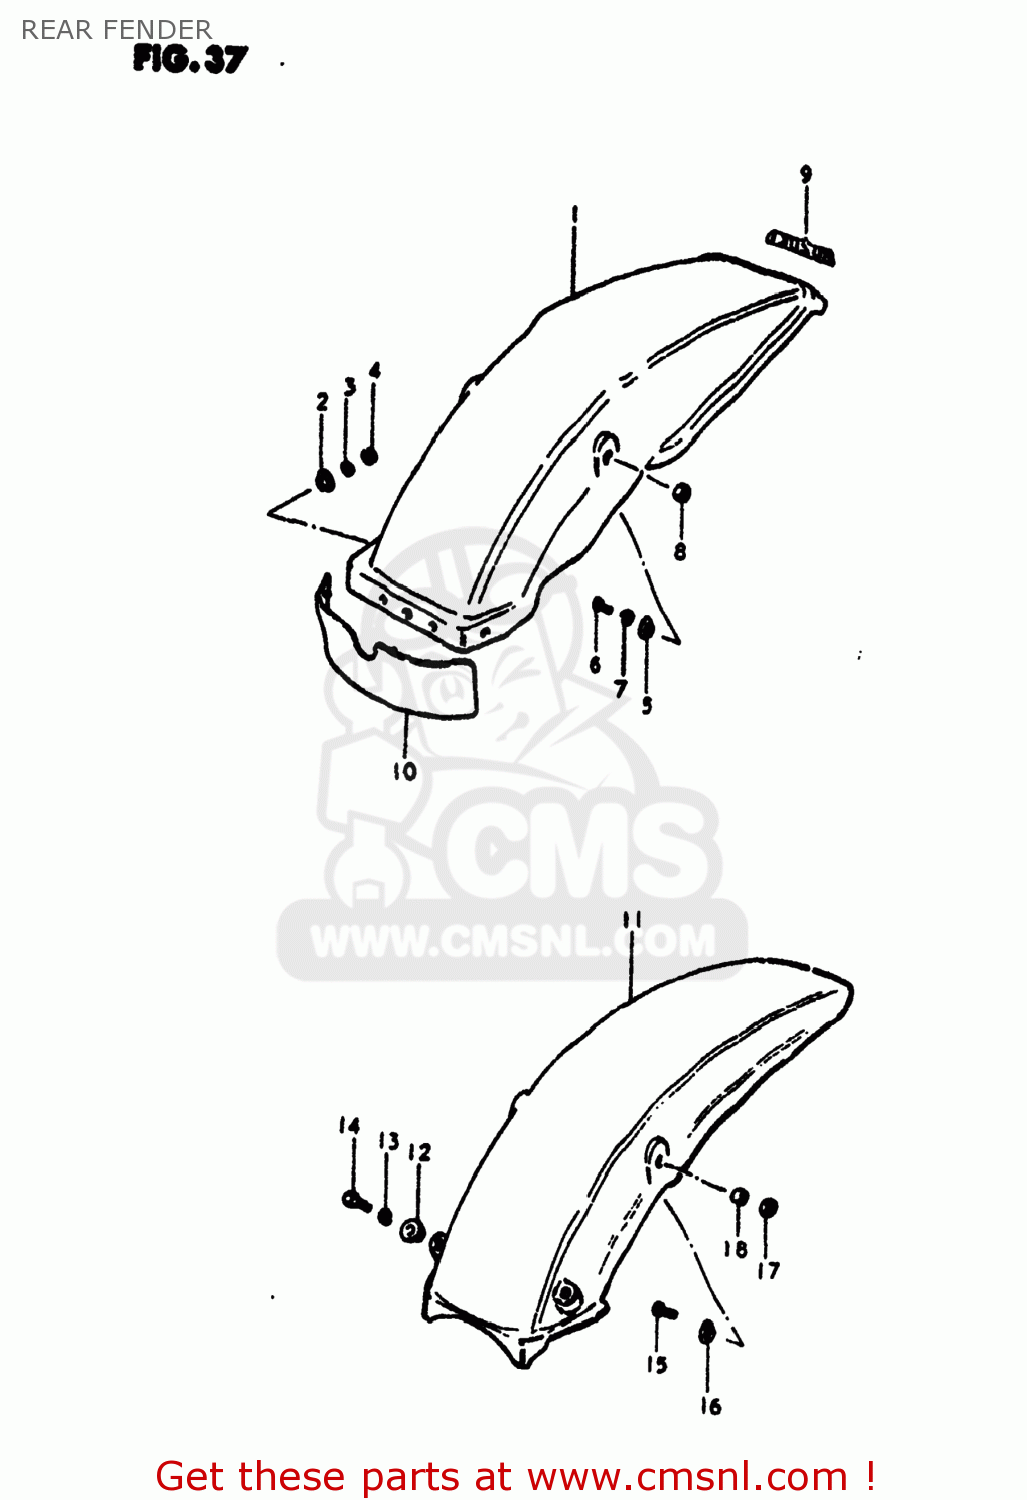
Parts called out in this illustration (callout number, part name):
1	FENDER,REAR
2	WASHER
3	LOCK WASHER
4	NUT
5	WASHER
6	BOLT, UPPER
7	LOCK WASHER
8	NUT 6MM
9	EMBLEM,FRONT FENDER
10	MUD GUARD,REAR FENDER
11	FENDER,REAR
12	WASHER
13	LOCK WASHER
14	BOLT, UPPER
15	SCREW
16	WASHER (6.5X20X1.2)
17	NUT
18	SPACER
